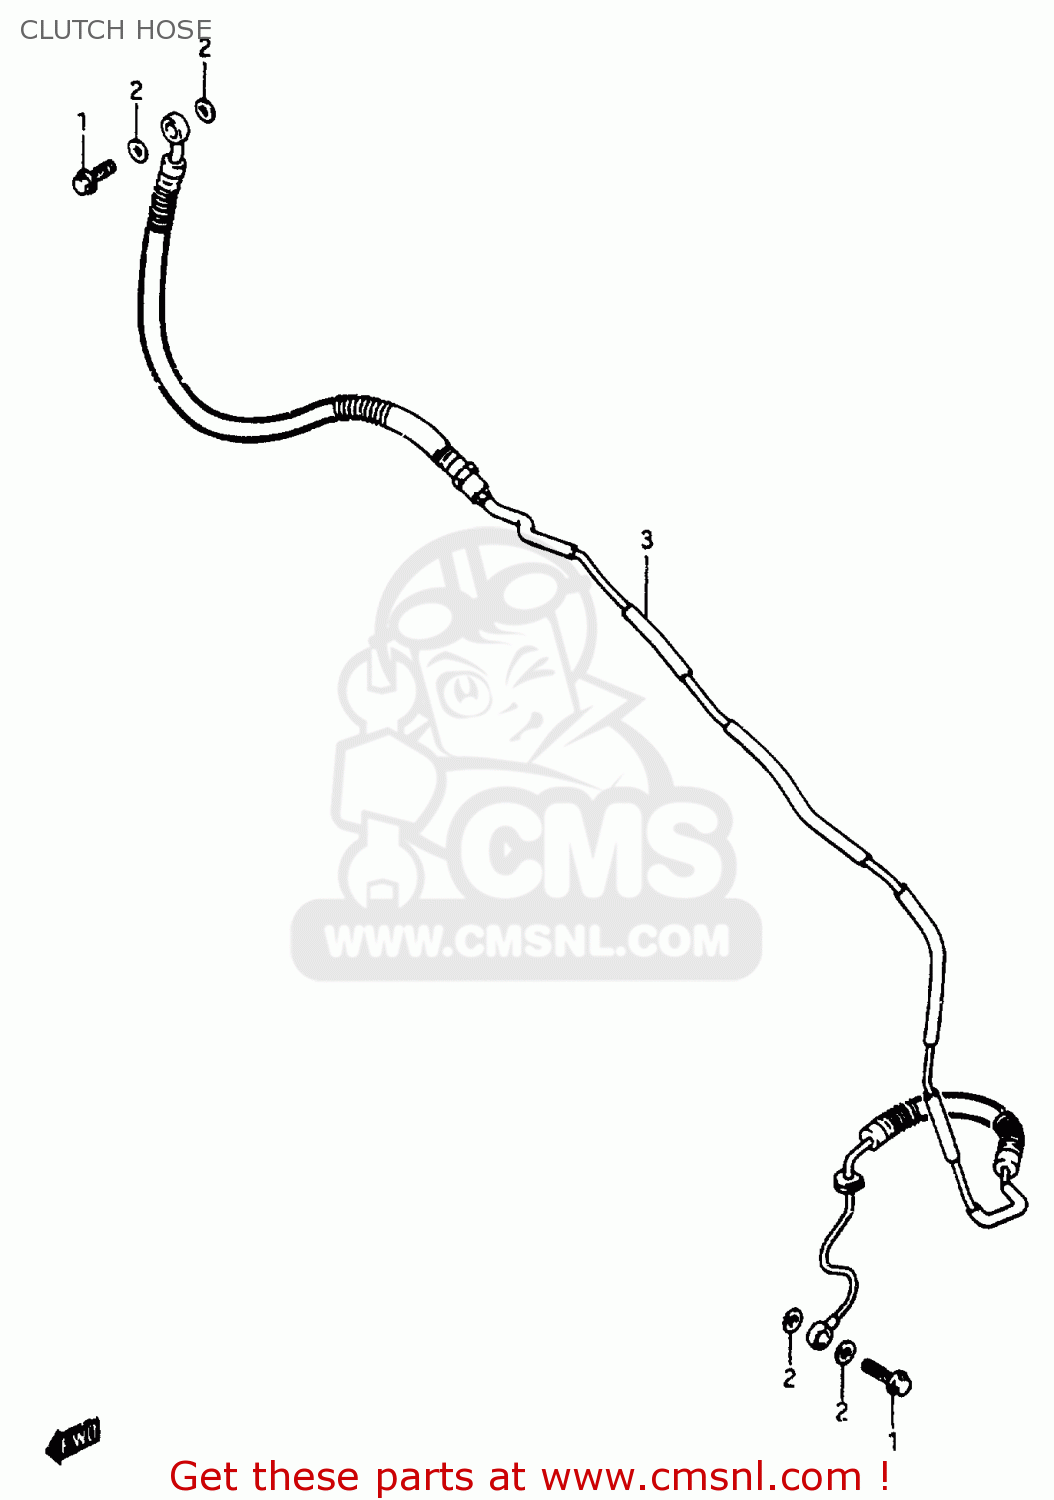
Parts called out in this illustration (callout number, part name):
1	BOLT UNION
2	WASHER(10X15X1.5)
3	HOSE ASSY,CLUTCH
